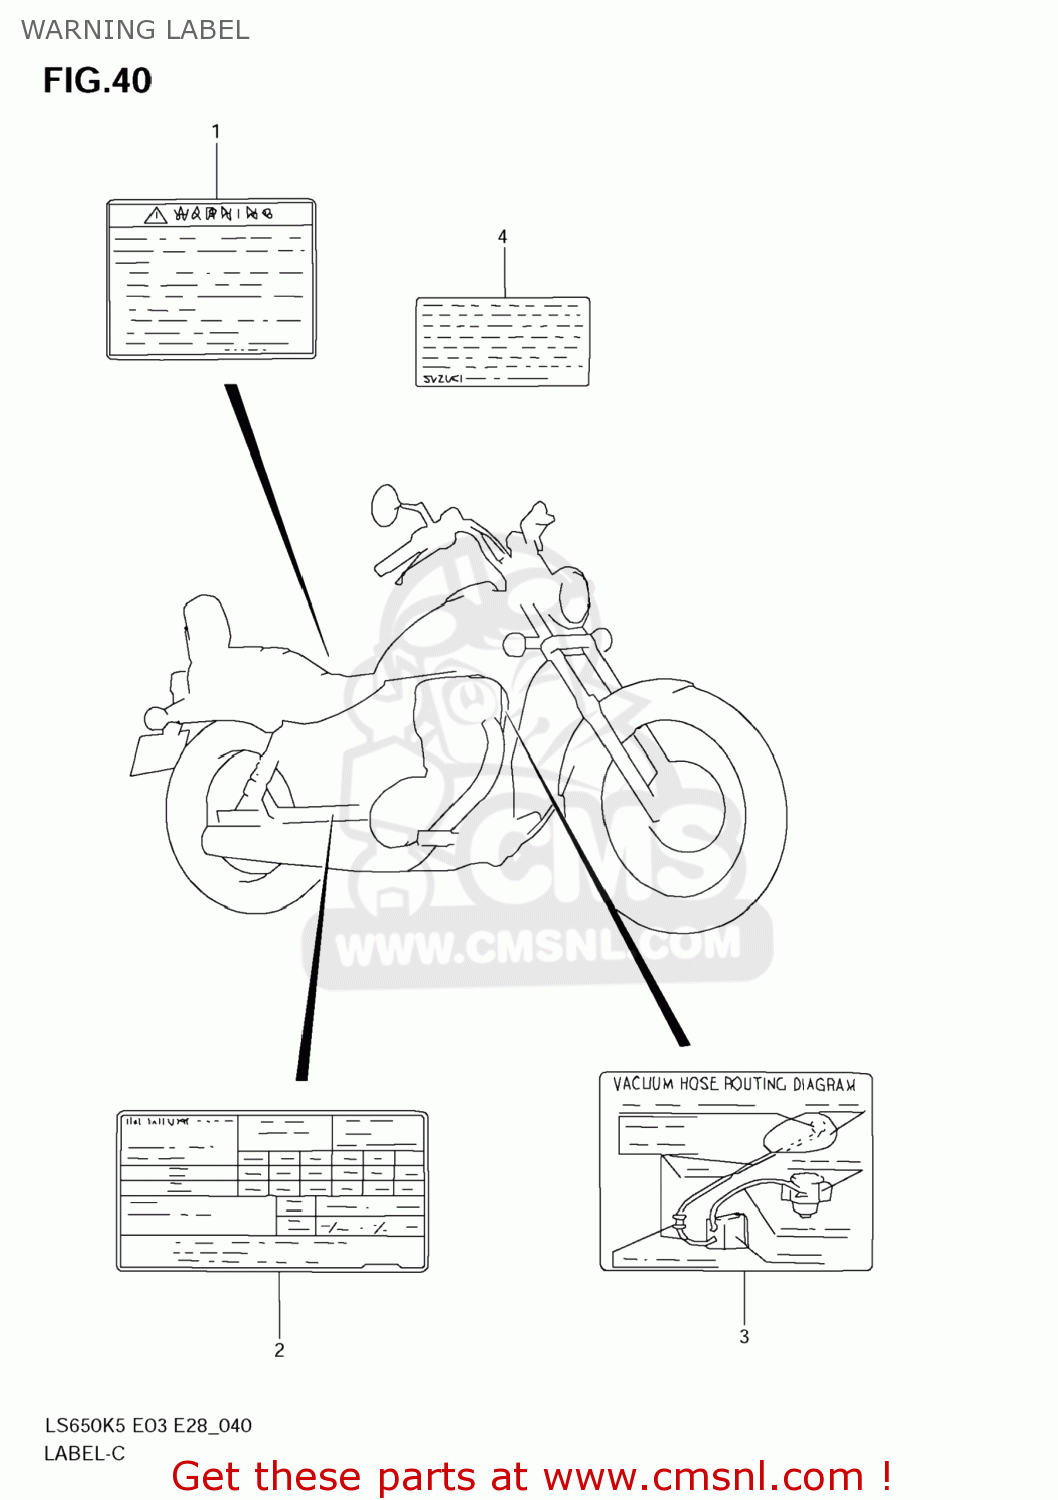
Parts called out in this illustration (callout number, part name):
1	LABEL,GENERAL WARNING
2	LABEL,TIRE INFORMATION
3	LABEL (VACUUM HOSE ROUTING)
4	LABEL,MANUAL NOTICE
5	MANUAL,OWNER'S
